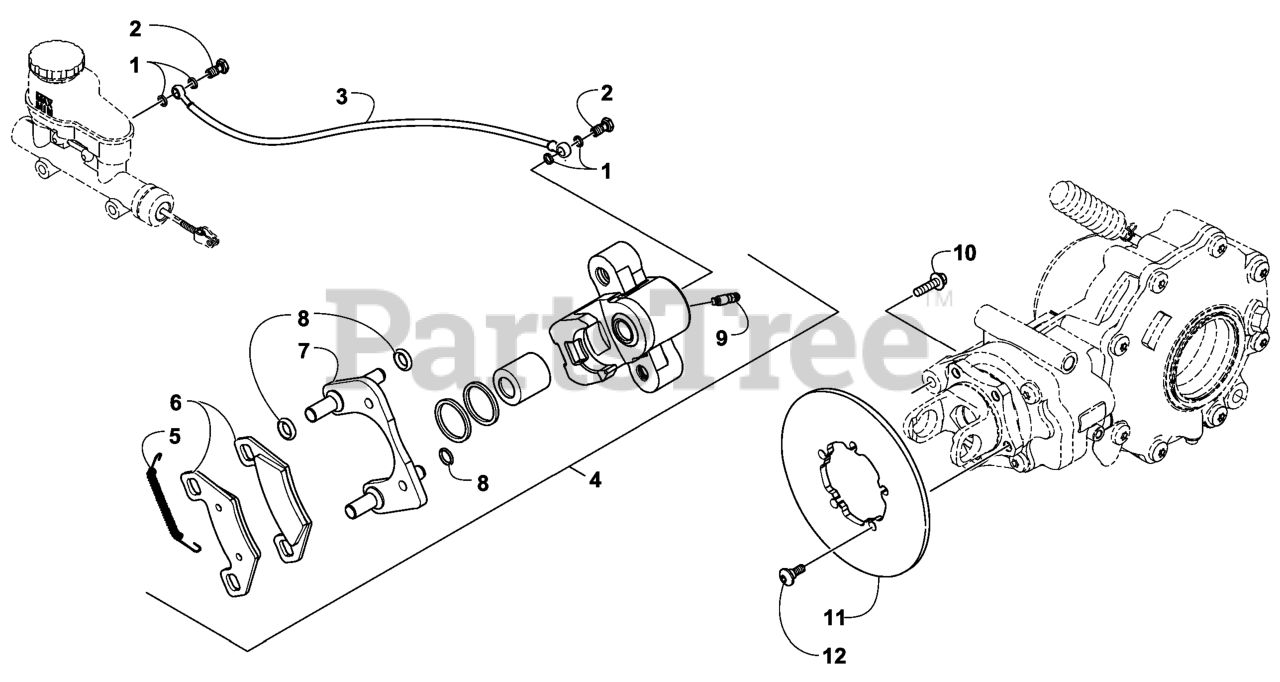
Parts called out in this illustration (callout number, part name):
1	WASHER-CRUSH
2	BOLT-BANJO FITTING
3	HOSE-BRAKE
4	KIT-1 INCH DRIVELINE/HYD
5	KIT-PAD SPRINGS (ANTI/RAT
6	KIT-BRAKE PAD (SET)
7	BRACKET ASM
9	BLEEDER-CALIPER
10	SCREW-HFH
11	ROTOR-MACH
12	SCREW-SHOULDER
